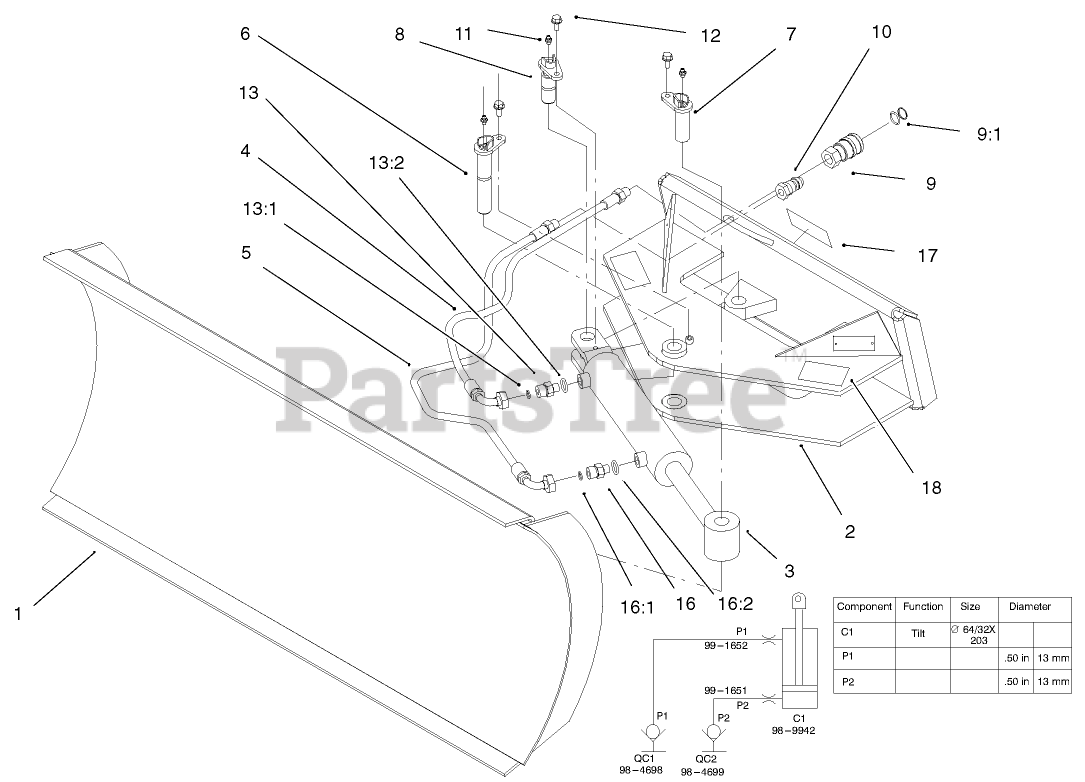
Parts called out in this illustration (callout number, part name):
2	BLADE PIVOT ASM
3	CYLINDER-HYD
4	HYD HOSE ASM
5	HYD HOSE ASM
6	PIN-PIVOT
7	PIN-PIVOT
9	FEMALE-DISCONNECT, QUICK
10	MALE-DISCONNECT, QUICK
11	FITTING-GREASE
12	SCREW-HWHTF
13	FITTING-STRAIGHT
13:1	O-RING
13:2	O-RING
16	FITTING-STR,ORIF
16:1	O-RING
16:2	O-RING
18	DECAL-WARNING
